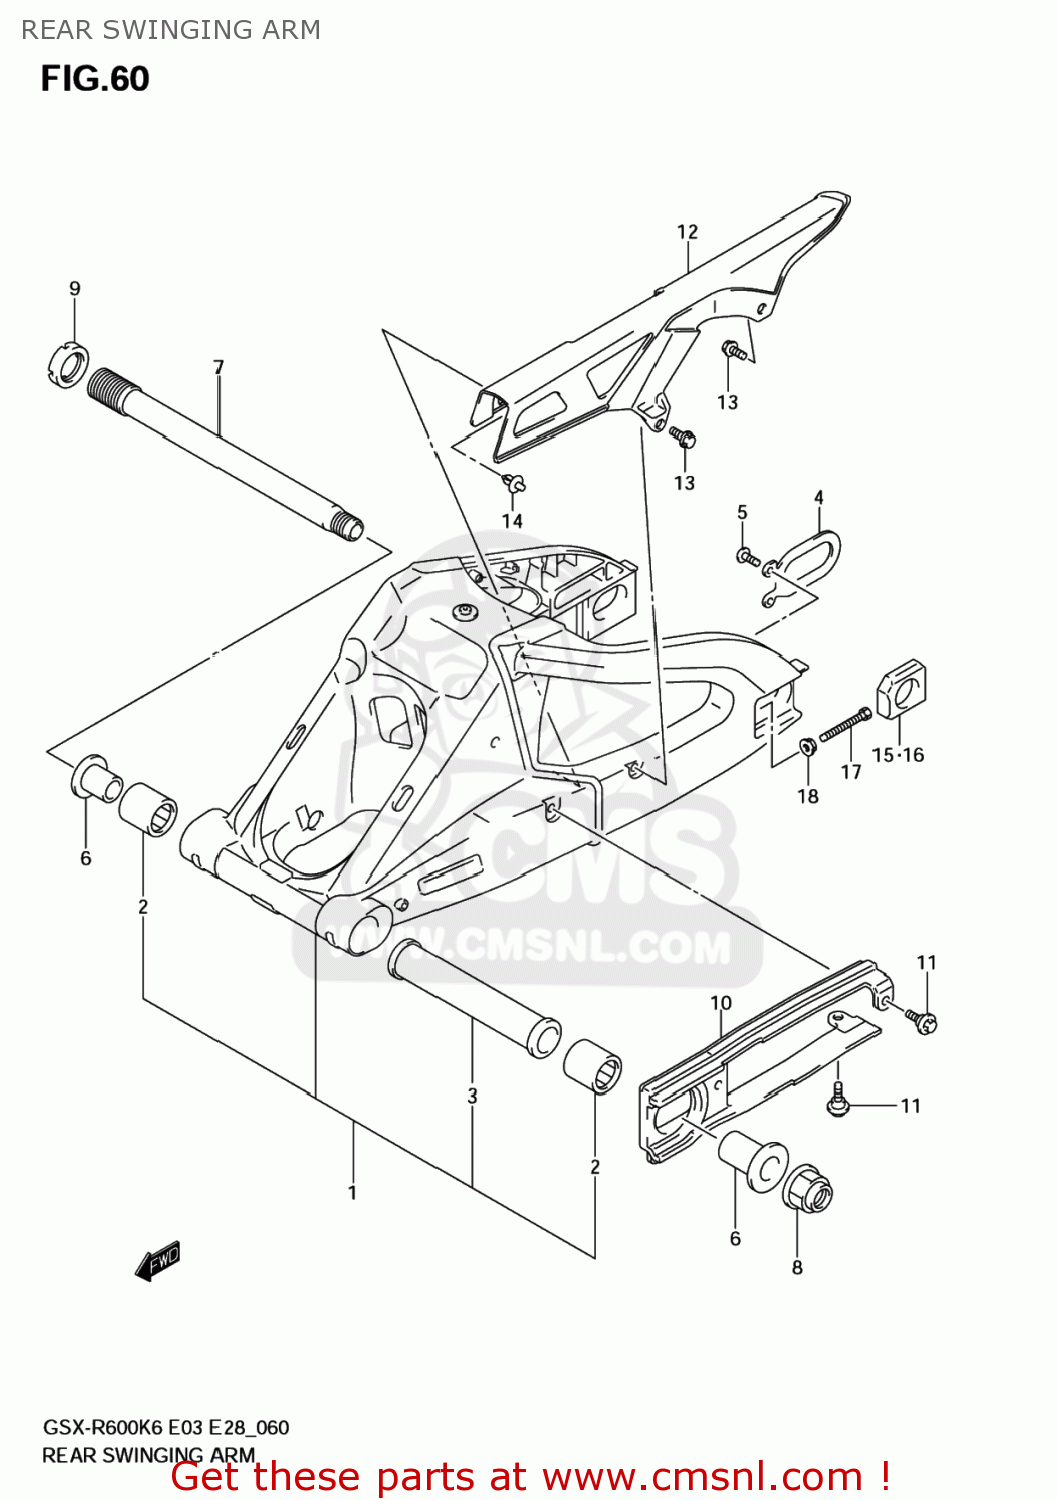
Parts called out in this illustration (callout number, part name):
1	SWINGINGARM ASSY,RR
2	BEARING(27X35X35)
3	SPACER,RR SWG PVT CTR
4	PLATE,RR SWGAR
5	SCREW (6X16)
6	SPACER,RR SWGA
7	SHAFT,RR SWINGINGARM PIVOT
8	NUT
9	NUT, PIVOT
10	BUFFER,CHAIN TOUCH DEFENSE
11	BOLT,BATTERY H
12	CASE,CHAIN NO.
13	BOLT(6X14)
14	CLIP(BLACK)
15	ADJUSTER,CHAIN
16	ADJUSTER,CHAIN
17	BOLT (8X50)
18	NUT
